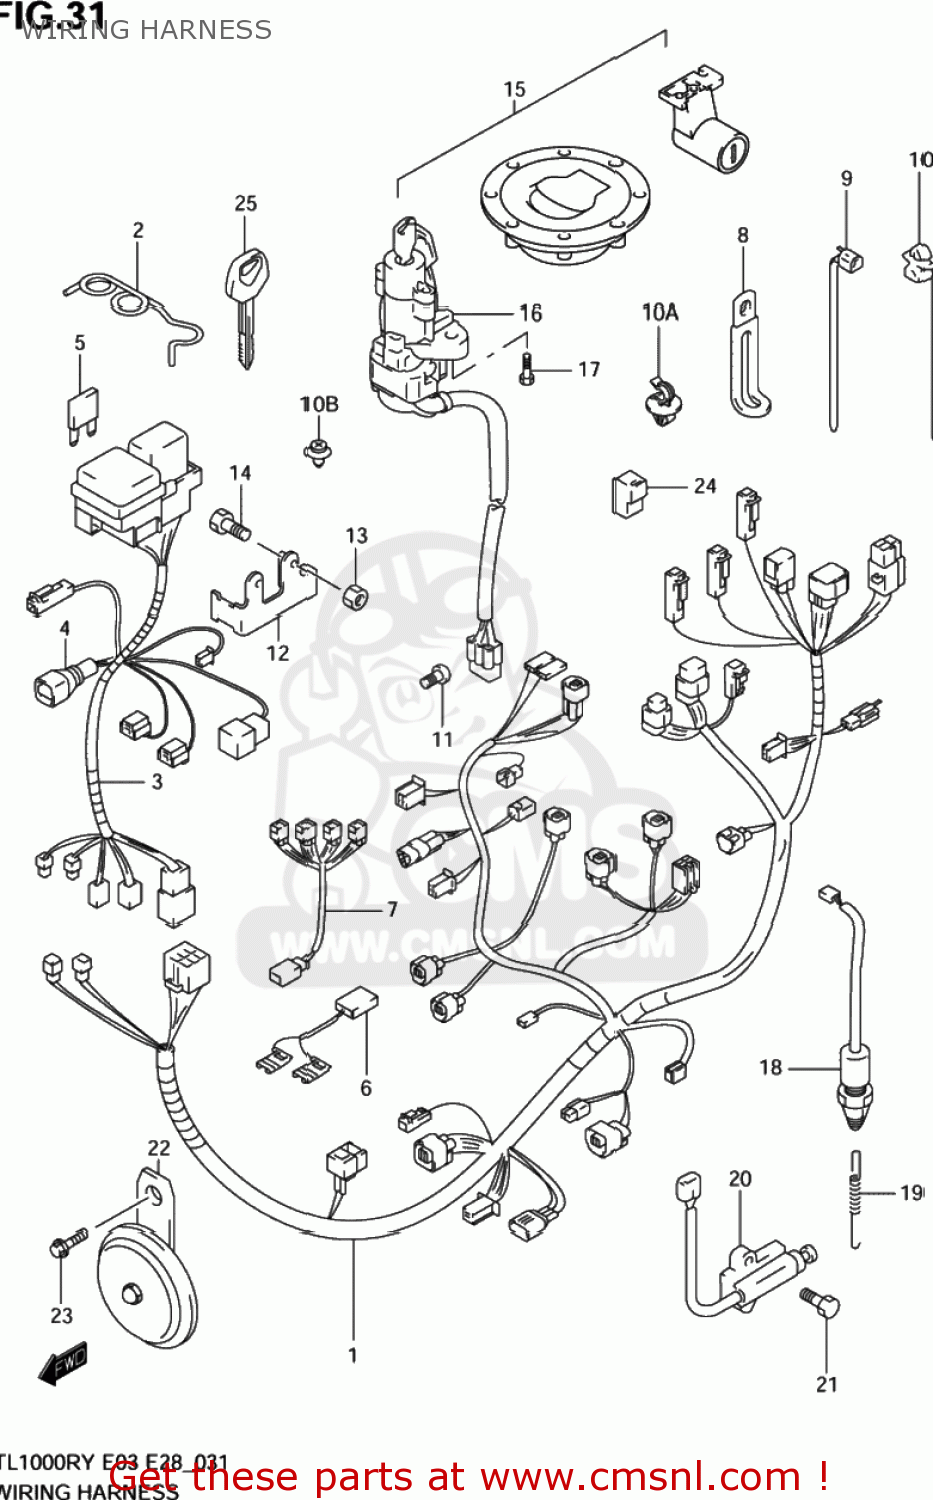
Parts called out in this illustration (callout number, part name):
1	HARNESS,WIRING NO.1
2	GUIDE,WIRING HARNESS
3	HARNESS,WIRING NO.2
4	COVER,SPEEDOMETER COUPLER
5	FUSE(10A)
6	WIRE,IGNITION COIL LEAD
7	WIRE,INJECTION LEAD
8	CLAMP(L:65)
9	CLAMP(L:125)
10	CLAMP
10A	CLAMP
10B	CLIP(BLACK)
11	BOLT
12	BRACKET,FUSE BOX
13	NUT,COWLING SCREEN
14	SCREW 5X12
15	LOCK SET
16	LOCK ASSY,STEERING
17	BOLT(8X20)
18	SWITCH ASSY,STOP LAMP
19	SPRING
20	SWITCH ASSY,SIDE STAND WARNING
21	BOLT
22	HORN ASSY
23	BOLT
24	RELAY ASSY
25	KEY,BLANK
